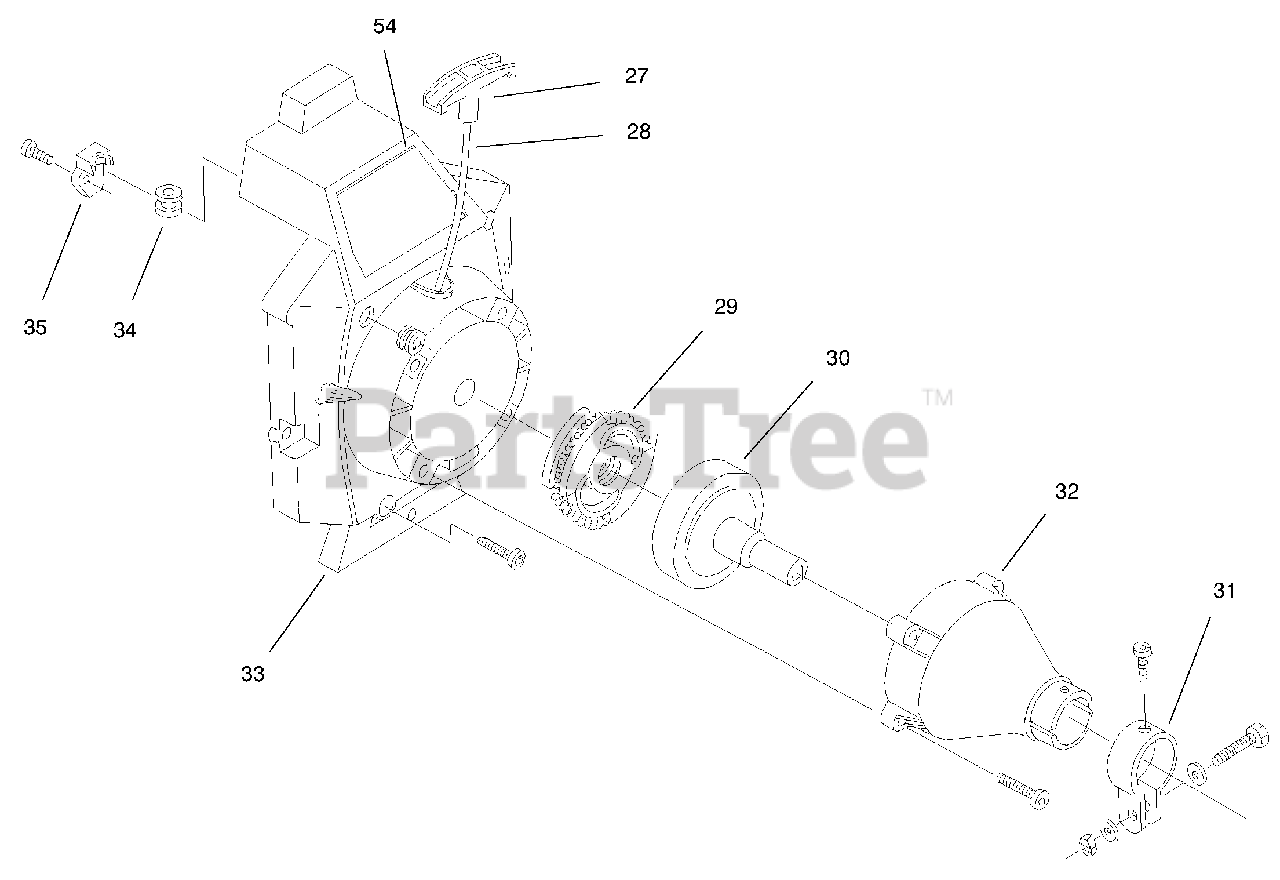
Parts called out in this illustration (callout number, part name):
27	Pull Handle
28	Starter Rope
29	Clutch Rotor Asm.
30	Clutch Drum Asm.
31	Clamp Asm.
32	Clutch Housing Asm.
33	Starter Housing Asm.
34	Rope Guide
35	Pulley Retainer
54	Decal-Toro
